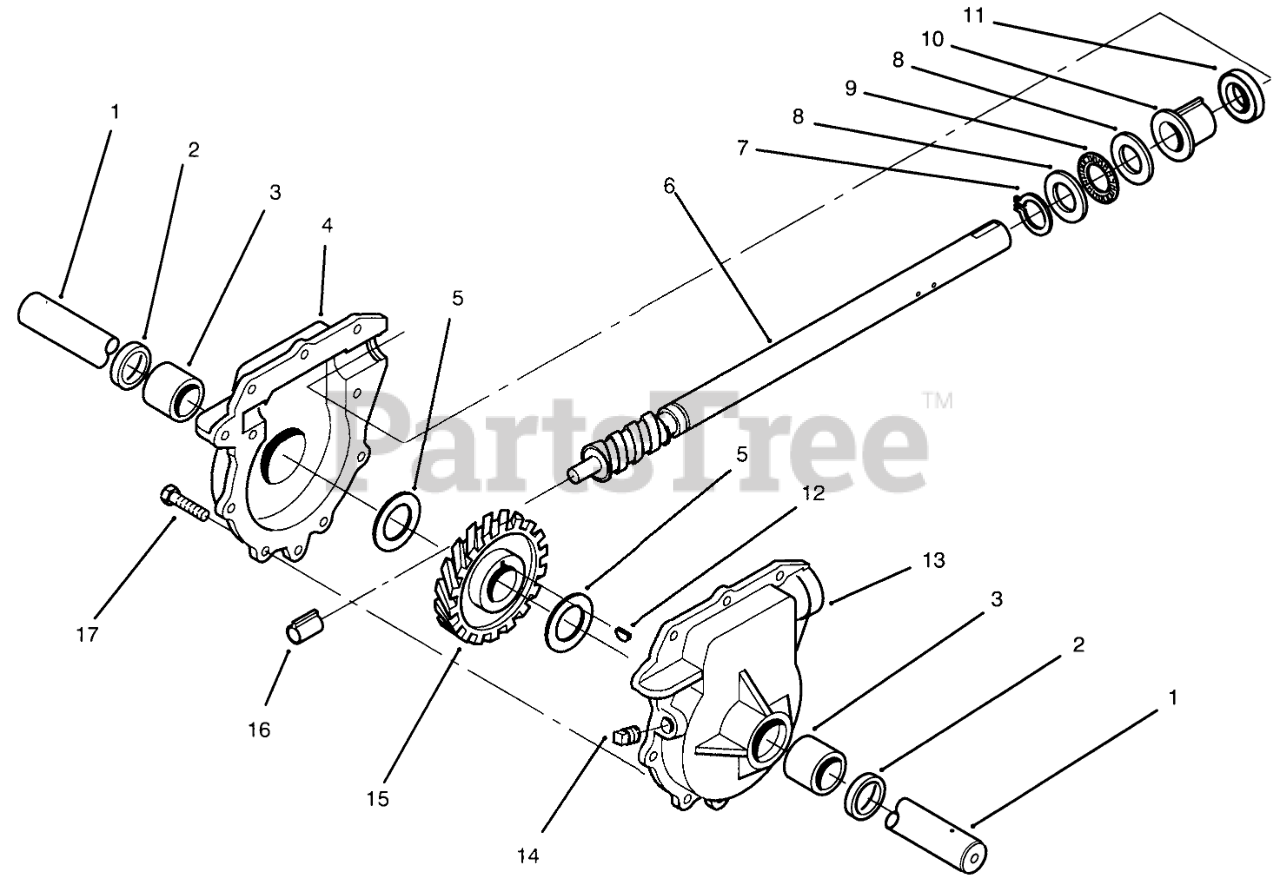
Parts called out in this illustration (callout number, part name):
1	SHAFT-AUGER
2	SEAL-OIL
3	BUSHING
4	Gearcase Assembly-R.H. (Incl. Ref. #2-3)
5	WASHER-THRUST
6	SHAFT-IMPELLER
7	RING-RETAINING, Ext
8	WASHER-THRUST
9	BEARING-THRUST
10	BUSHING-INPUT
11	SEAL-OIL
12	KEY-WOODRUFF
13	Gearcase Assembly-L.H. (Incl. Ref. #2-3, & 17)
14	PLUG-PIPE, SQH
15	GEAR-HELICAL
16	BUSHING-WORM
17	SCREW-HWH
